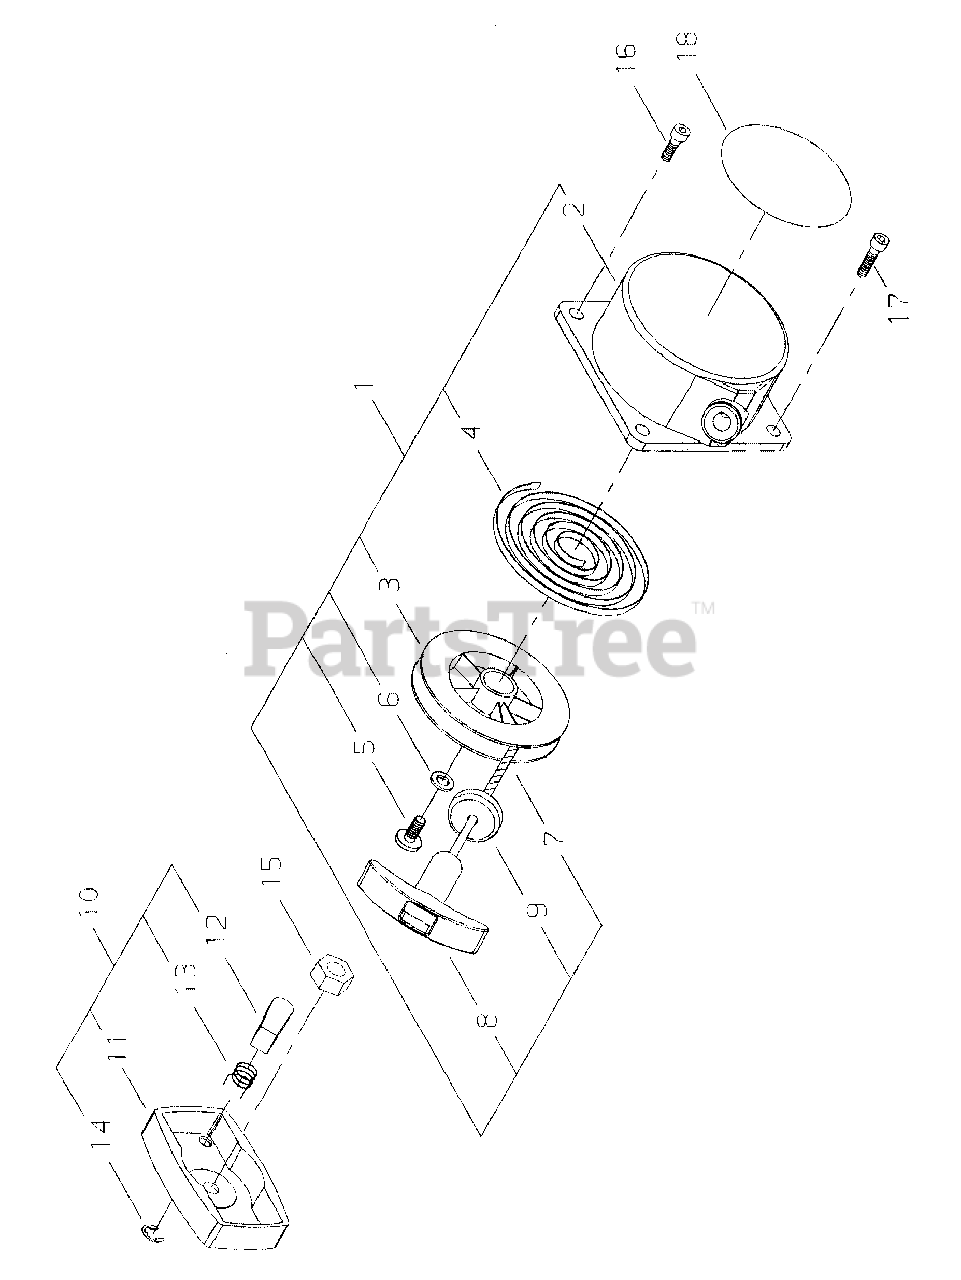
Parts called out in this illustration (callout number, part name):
1	STARTER ASSY
2	CASE, STARTER
3	REEL, ROPE
4	SPRING, REWIND
5	SCREW - 5
6	WASHER
7	ROPE, STARTER
8	GRIP, STARTER
9	GUIDE, ROPE
10	STARTER PAWL ASSY
11	REEL, ROPE
12	PAWL, STARTER
13	SPRING, RETURN
14	RING, RETAINING - 4
15	NUT
16	SCREW - 5X20
17	SCREW - 5X25
18	LABEL - TRADE
